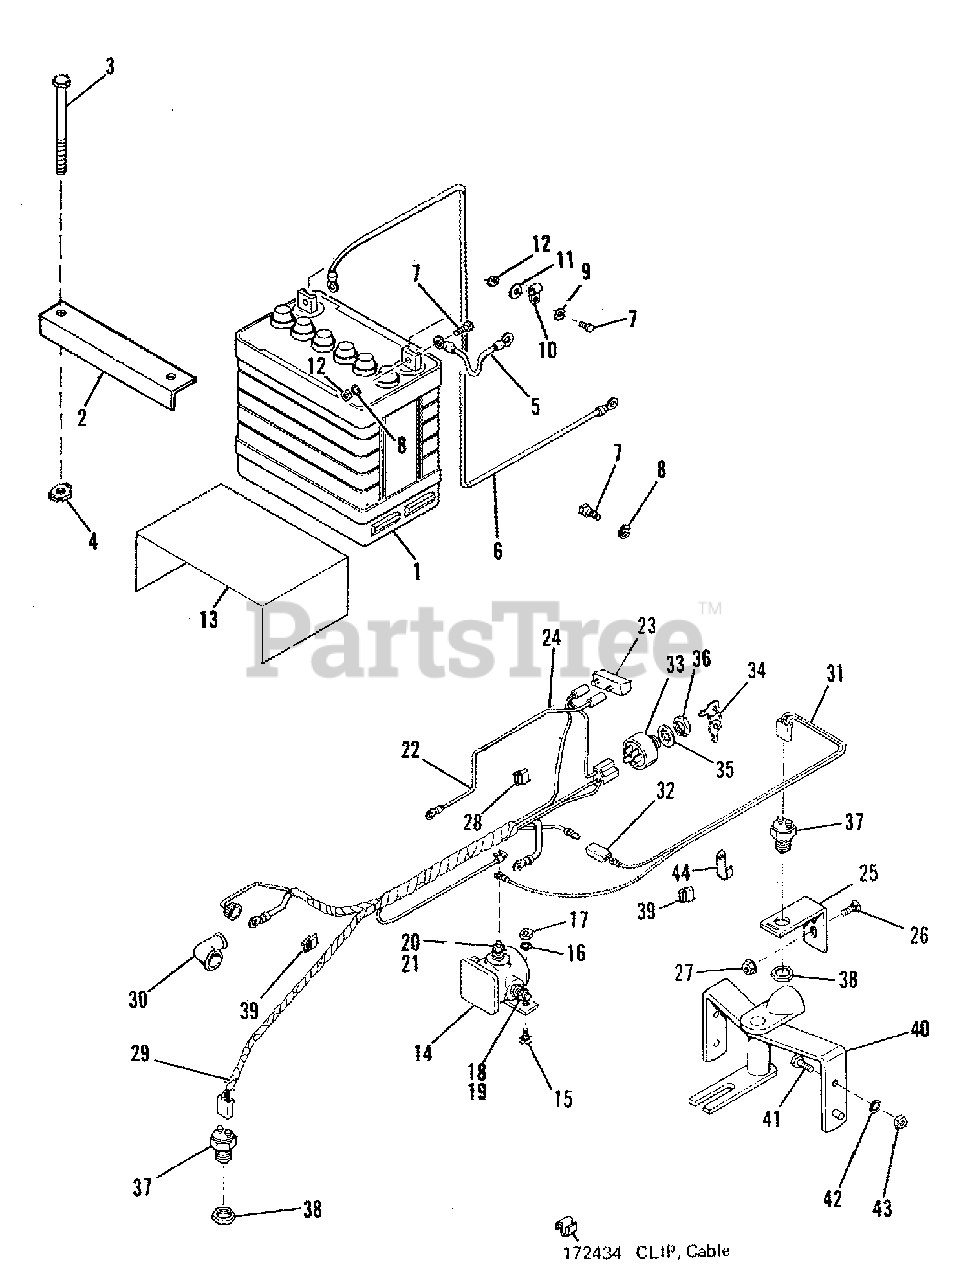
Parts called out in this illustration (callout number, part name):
2	HOLD DOWN, Battery
3	CAPSCRE, Hex, 1/4"-20 x 7" Large
4	NUT, Retainer, 1/4"-20
7	CAPSCREW, Hex, 1/4"-20 x 3/4" Large
8	LOCKWASHER, 1/4"
9	LOCKWASHER, 1/4"
11	WASHER, Plain, 1/4"
12	NUT, Full Hex, 1/4-20
13	INSULATION, Battery
15	BOLT, Carriage
16	LOCKWASHER, 1/4"
17	NUT, Full Hex, 1/4"-20
18	LOCKWASHER, 5/16"
19	NUT, Full Hex, 5/16-18"
20	LOCKWASHER, Shake-Proof No.10
21	NUT, Full Hex No.10-32
22	WIRE, Solenoid to Circuit Breaker
23	BREAKER, Circuit
24	WIRE, Neg. Amp to Solenoid
26	BOLT, Carriage, 1/4- x 3/4" Large
27	NUT, Flange, 1/4"-20
28	CLIP, Cable
29	HARNESS ASSEMBLY
30	COVER, Terminal
31	WIRE, Safety Switch
32	CONNECTOR, Insulator
33	SWITCH, Ignition
34	KEY & RING ASSEMBLY
35	LOCKWASHER, 5/8" Int.
36	NUT, Special
37	SWITCH, Safety
38	NUT, Pal, 9/16-18
39	CLIP, Speed
40	PIVOT ASSEMBLY
41	CAPSCREW, 5/16-18 x 3/4" Large
42	LOCKWASHER, 5/16"
43	NUT, Full Hex, 5/16-18"
44	J" CUP, Open`
